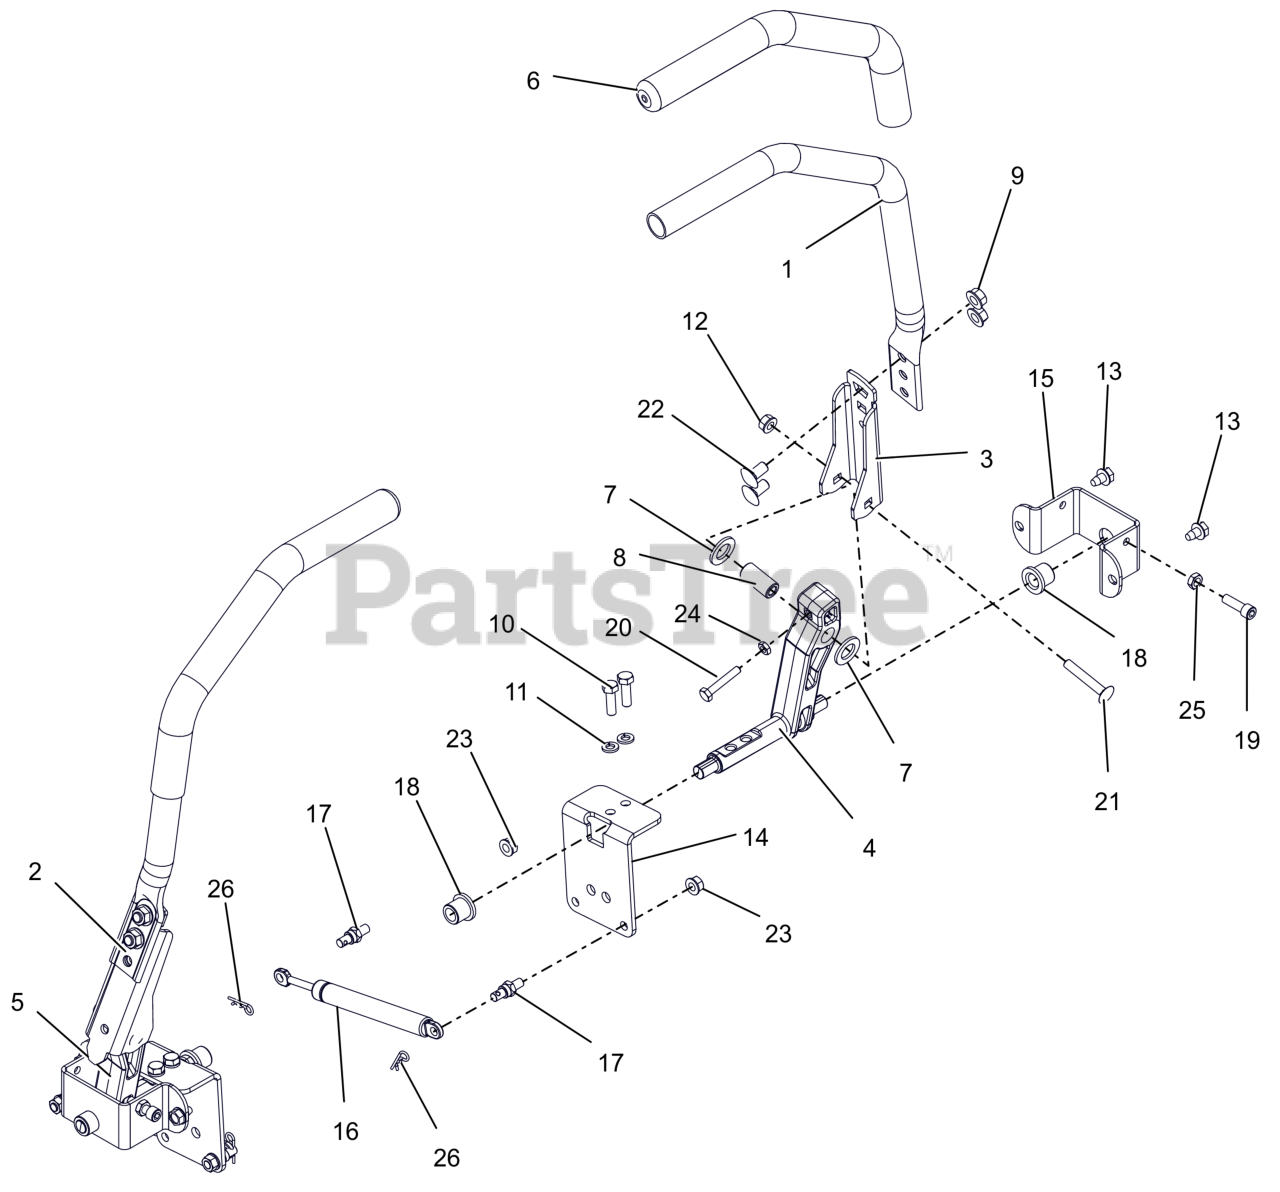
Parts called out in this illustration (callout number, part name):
1	HANDLE, STEERING-LH
2	HANDLE, STEERING-RH
3	ARM, CONTROL UPPER
4	STEERING, LH LWR CAST ARM
5	STEERING, RH LWR CAST ARM
6	GRIP, HANDLEBAR 15" FOAM
7	WSHR, FRICTION
8	BSHG-SLV .342 X .627 X 1.331
9	NUT-LK-CTR-FLG .375-16 GF ZCC
10	BLT, HEX .31-18X1.00 G8 ZCC
11	WSHR,LK-REG .312X.078 ZCC
12	NUT,LK-CTR-FLG .31-18 GF ZCC
13	SCR,TAP .312-18X.50 HWH TR ZCC
14	BRKT, STEEERING
15	BRKT, STEERING
16	DAMPER, STRAIGHT MOUNT
17	COUPLER, DAMPER MOUNT
18	BHSG-FLG .500X.750X.750X.125
19	SCR, SKH .312-18X1.00 G8 SS
20	BLT, HEX .25-20X1.50F G5 ZCC
21	BLT, RHSSN .31-18X2.00 G5 ZCC
22	BTL,RHSSN .375-16 X 0.75 G5 FPB
23	NUT-LK-TOP-FLG .312-18 GF ZCC
24	NUT-JAM .250-20 G2 ZCC
25	NUT-JAM .312-18 G2 ZCC
26	PIN, HAIR #213 .08X1.19 ZCC
